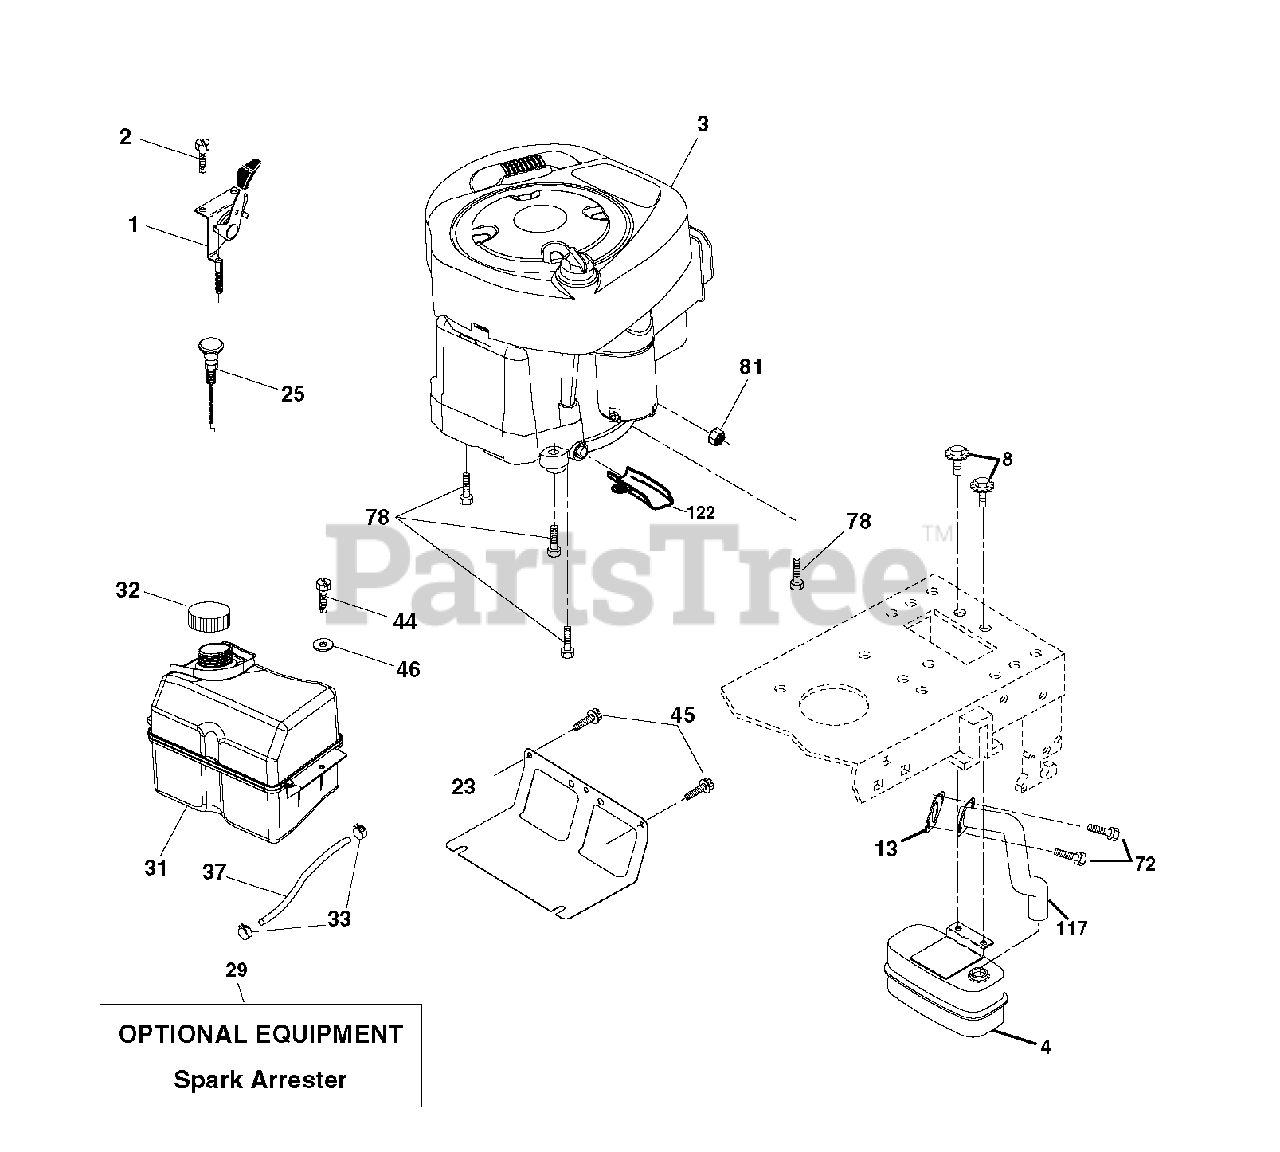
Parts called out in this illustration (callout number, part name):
1	CONTROL TH/CH FLAG
2	SCREW
4	MUFFLER.SINGLE.CYL.KOHL/B&S
8	BOLT, 5/16-18 X 1 3/4
13	REPL BY 532 27 22-93
23	SHEILD.BROWNING.DBR.GUARD
29	ARRESTER SPARK (OPTIONAL)
32	CAP.FUEL.2.25"VENTED"
33	HOSE CLAMP
37	LINE.FUEL.20
44	SCREW HEXWSHR 1/4-20X3/4
45	SCREW, 3/8-16X3/4
72	SCREW.SOCKET HD.5/16-1
78	SCREW.3/8-16
81	NUT
117	EXHAUST.TUBE.B&S.
122	EXTENSION DRAIN OIL
